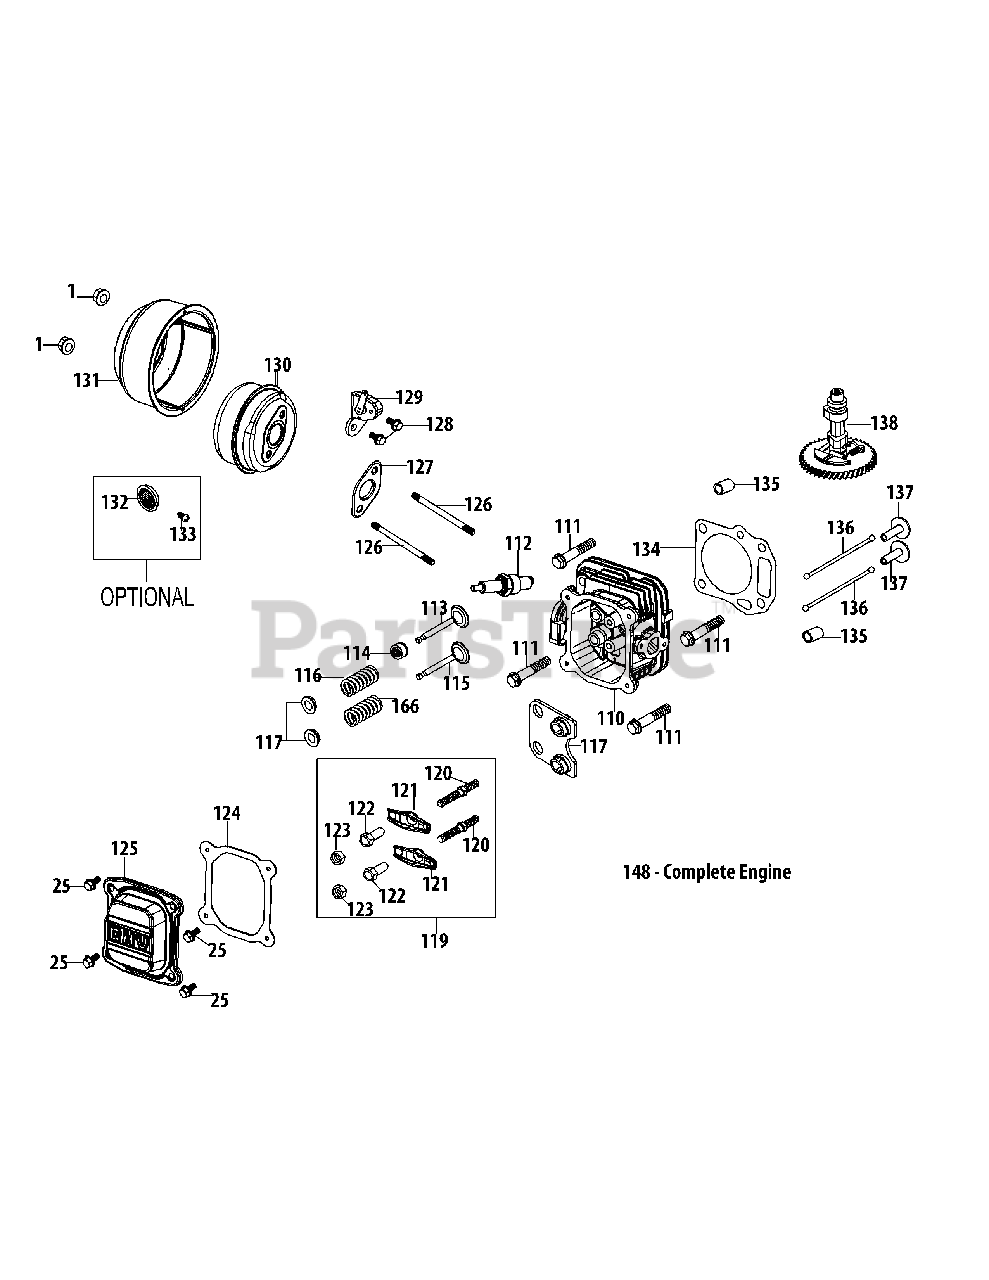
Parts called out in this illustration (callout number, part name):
1	Nut M6X10Mm Starter/Carb/Muff
25	Bolt M6×14 Multi-Purpose
110	Cylinder Head Assy
110	Cylinder Head
111	Bolt M8X54 Cylinder Head
112	Spark Plug/F5Rtc
113	Intake Valve
114	Intake Valve Seal
115	Exhaust Valve
116	Valve Spring
117	Valve Spring Retainer
118	Push Rod Guide
119	Rocker Arm Assembly
120	Rocker Arm Stud
121	Rocker Arm
122	Fulcrum Nut
123	Jam Nut
124	Valve Cover Gasket
125	Valve Cover
126	Muffler Stud M6×76
127	Muffler Gasket
128	Bolt M6X12 Multi-Purpose
129	Choke Temp Control Thermostat
130	Muffler Assembly
131	Muffler Shield
132	Spark Arrestor
133	Spark Arrestor Screw
134	Cylinder Head Gasket
135	Cylinder Head Dowel Pin 10×16
136	Push Rod
137	Tappet
138	Camshaft Assembly
148	Complete Engine
